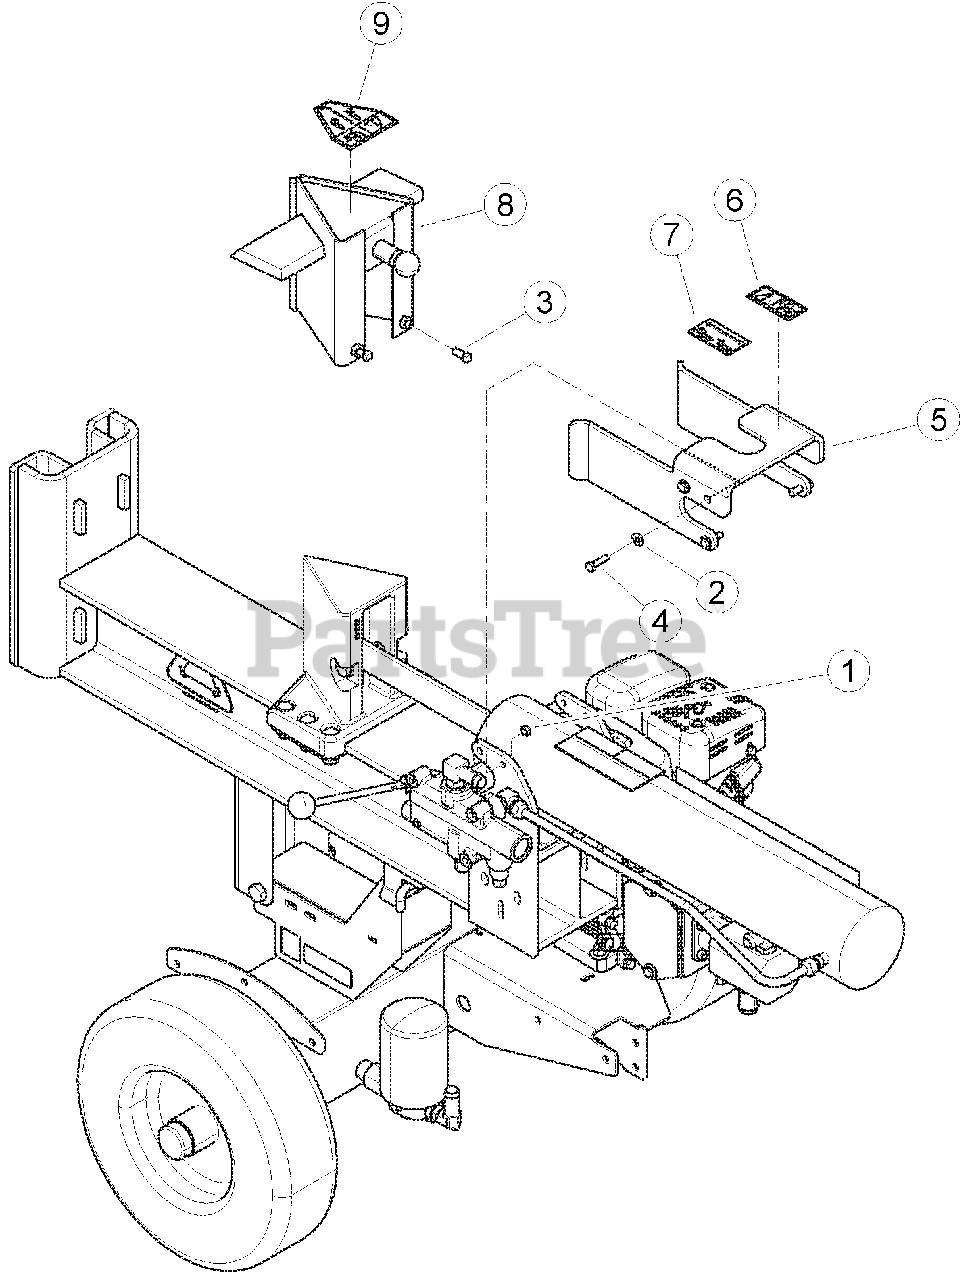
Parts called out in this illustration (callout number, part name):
1	NUT 5/16 CENTERLOCK NC ZP
2	WASHER, 5/16 FLAT ZP
3	SCREW, 3/8 X 3/4 SQ HD SET ZP
4	BOLT, 5/16 X 1-1/4 HEX HD GR5 NC ZP
5	PLATE, LOG STRIPPER, SERVICE PART
6	DECAL, CRUSHING ISO
7	DECAL, CYLINDER OPERATION (ISO)
8	WELDMENT, 4 WAY WEDGE, SERVICE PART
9	DECAL, WEDGE CAUTION
